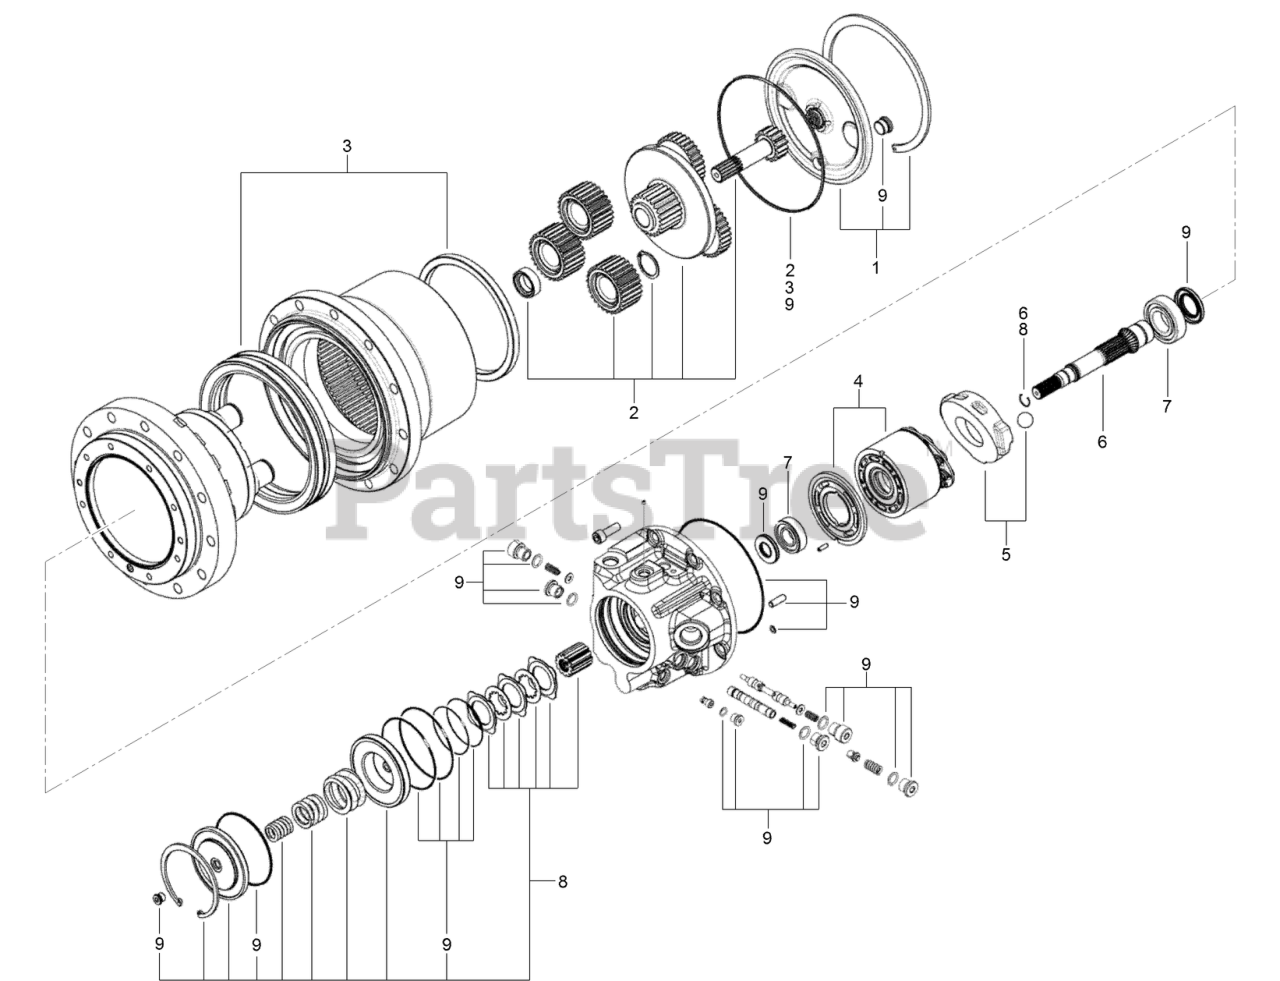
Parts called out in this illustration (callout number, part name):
1	COVER ASM
2	REDUCTION ASM
3	SEAL KIT
4	CYLINDER BLOCK ASM
5	SWASHPLATE KIT
6	MOTOR SHAFT ASM
7	BEARINGS KIT
8	PARKING BRAKE KIT
9	SEAL KIT
